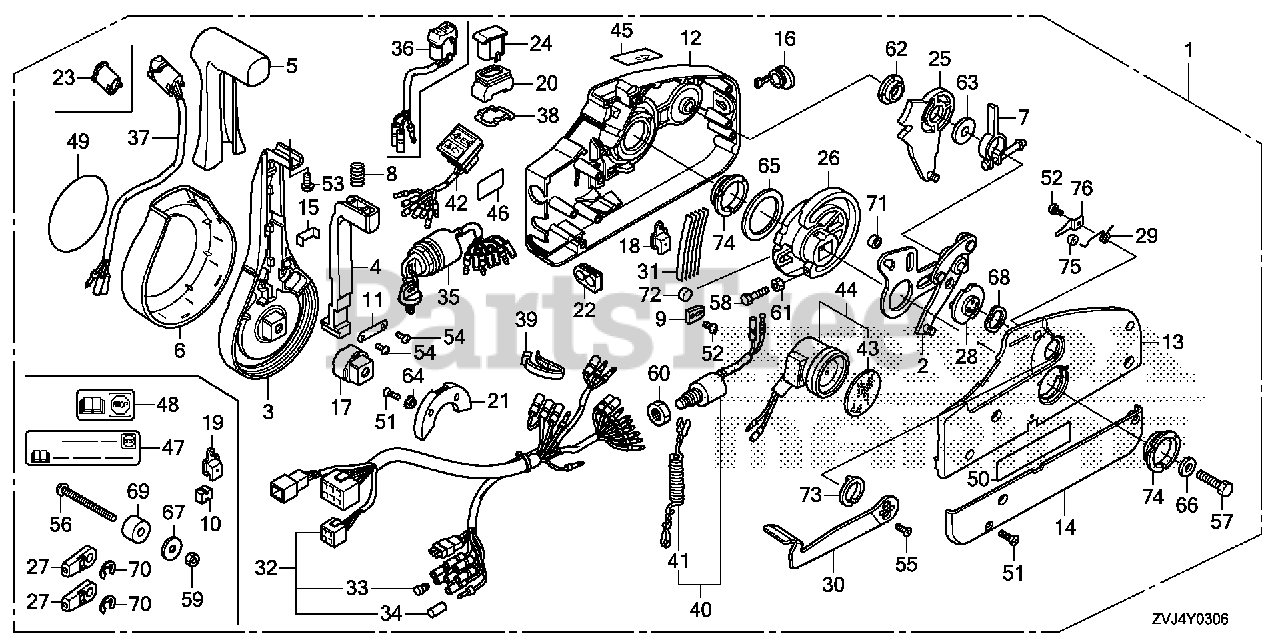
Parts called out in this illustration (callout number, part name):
1	BOX ASSY., REMOTE CONTROL (4-LED) (NHK MEC)
1	BOX ASSY., REMOTE CONTROL (NHK MEC)
1	BOX ASSY., REMOTE CONTROL (TROLLING CONTROL)(NHK MEC)
2	PLATE ASSY.
3	LEVER, HAND
4	ARM, NEUTRAL LOCK
5	GRIP
6	COVER, LEVER
7	ARM ASSY., BRAKE
8	SPRING (2)
9	CLIP, DETENT
10	SPACER (1)
11	BRACKET
12	HOUSING, FR.
13	HOUSING, RR.
14	PANEL, BACK
15	BRACKET, WIRE CLAMP
16	CAP, RUBBER
17	ADJUSTER
18	COVER, POWER TRIM-TILT WIRE
19	COVER, POWER TRIM-TILT WIRE (LOOSE PARTS)
20	SEAL, RUBBER
21	HOLDER, NEUTRAL LOCK
22	GROMMET, WIRE (14)
23	COVER, GRIP
24	CAP, TROLLING CONTROL SWITCH BLANK
25	GEAR ASSY., SHIFT
26	GEAR, DRIVE
27	TERMINAL, CABLE (LOOSE PARTS)
28	DRUM ASSY., FREE THROTTLE
29	SPRING (1)
30	LEVER, FREE THROTTLE
31	SPRING, DETENT
32	CABLE ASSY., REMOTE CONTROL (B)
32	CABLE ASSY., REMOTE CONTROL (B)(TROLLING CONTROL)
33	PLUG, CONNECTOR (INNER)
34	PLUG, CONNECTOR (OUTER)
35	SWITCH ASSY., COMBINATION
36	SWITCH ASSY., TROLLING CONTROL
37	SWITCH ASSY., POWER TRIM-TILT
38	PLATE, SWITCH
39	BAND, WIRE
40	SWITCH ASSY., EMERGENCY STOP
41	WIRE, EMERGENCY
42	LAMP ASSY., INDICATION
43	PLATE, TURN SIGNAL BUZZER
44	BUZZER, WARNING
45	MARK, FAST IDLE
46	MARK, EMERGENCY STOP (US)
47	MARK, EMERGENCY STOP (US) (LOOSE PARTS)
49	MARK, EMBLEM
50	LABEL, SIGP
51	SCREW (5X18)
52	SCREW (4X6)
53	SCREW (5X10)
54	SCREW (4X10)
55	SCREW (5X12)
56	SCREW (6X90) (LOOSE PARTS)
57	BOLT (8X50)
58	BOLT (5X25)
59	NUT (6MM) (LOOSE PARTS)
60	NUT, HEX. (16MM)
61	NUT (5MM)
62	BEARING (1)
63	WASHER (3)
64	WASHER (4)
65	WASHER (5)
66	WASHER (8MM)
67	WASHER (7) (LOOSE PARTS)
68	WASHER, WAVE
69	SPACER (2) (LOOSE PARTS)
70	E-RING (6MM) (LOOSE PARTS)
71	ROLLER, DRIVE GEAR CAM
72	ROLLER
73	BEARING (2)
74	BEARING (3)
75	ROLLER, FREE THROTTLE
76	CLIP, ROLLER
